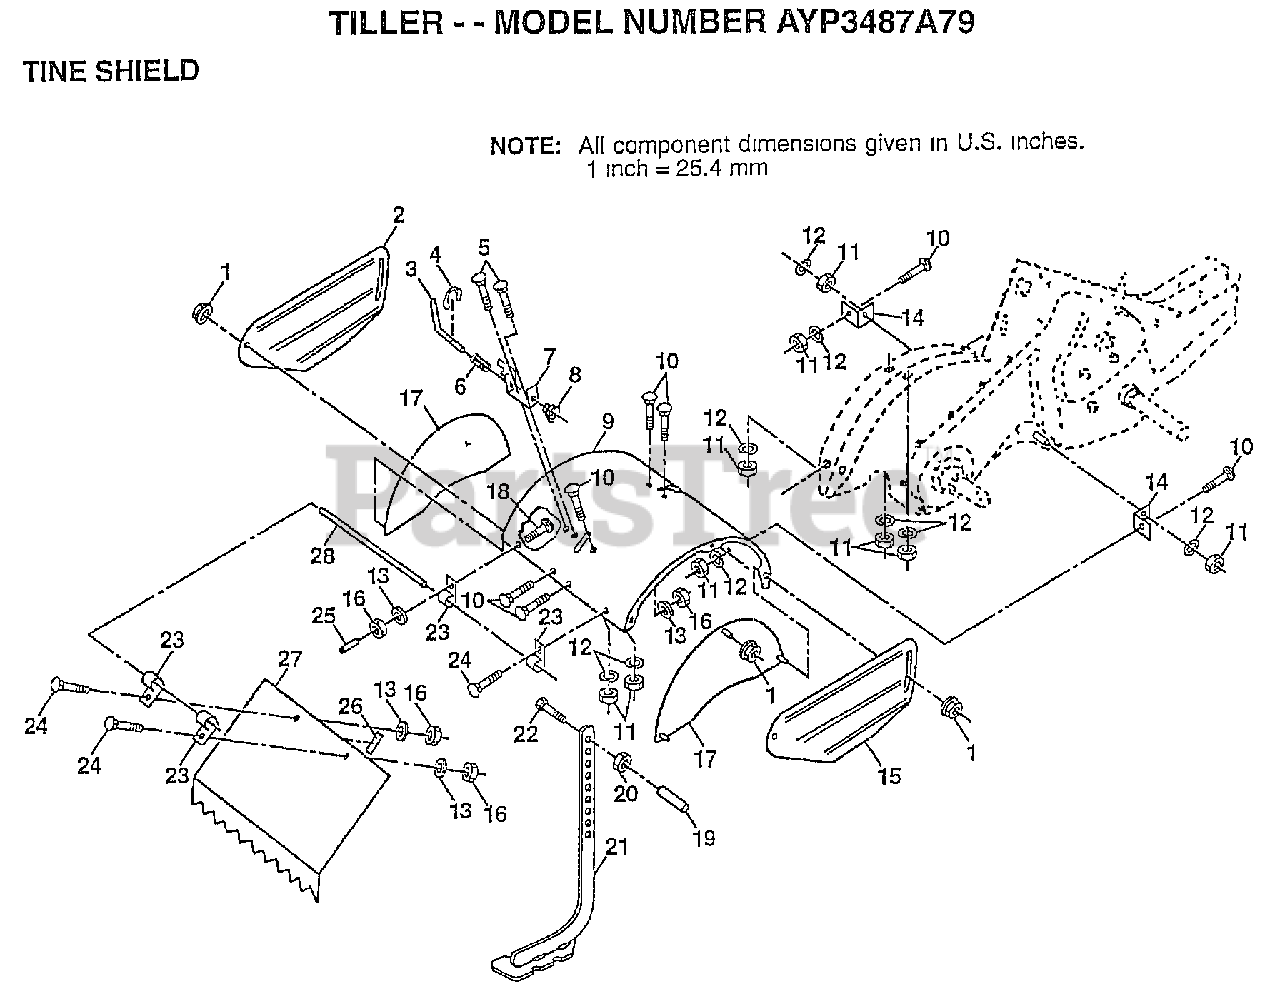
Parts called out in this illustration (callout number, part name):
1	NUT
2	SHIELD SIDE OUT L
3	STAKE PIN TI
4	KLIP RING TI
5	BOLT
6	SPRING TI
7	LATCH BRACKET TI
8	SPRING CRT
9	SHIELD TINE RED
10	BOLT
11	NUT.HEX.5/16-18
12	LOCKWASHER
13	LOCKWASHER
14	TINE SHLD BRKT TI
15	SHIELD SIDE RH
17	SHIELD SIDE RED
18	BOLT
19	GRIP CRT
20	NUT.HEX.3/8-16UNC
21	STAKE.ASM.DEPTH
22	BOLT
23	HINGE CRT
24	BOLT.1/4-20X1/2
25	VINYL CAP TI
26	PAD IDLER TI
27	SHIELD LEVELING
28	PIN.HINGE
